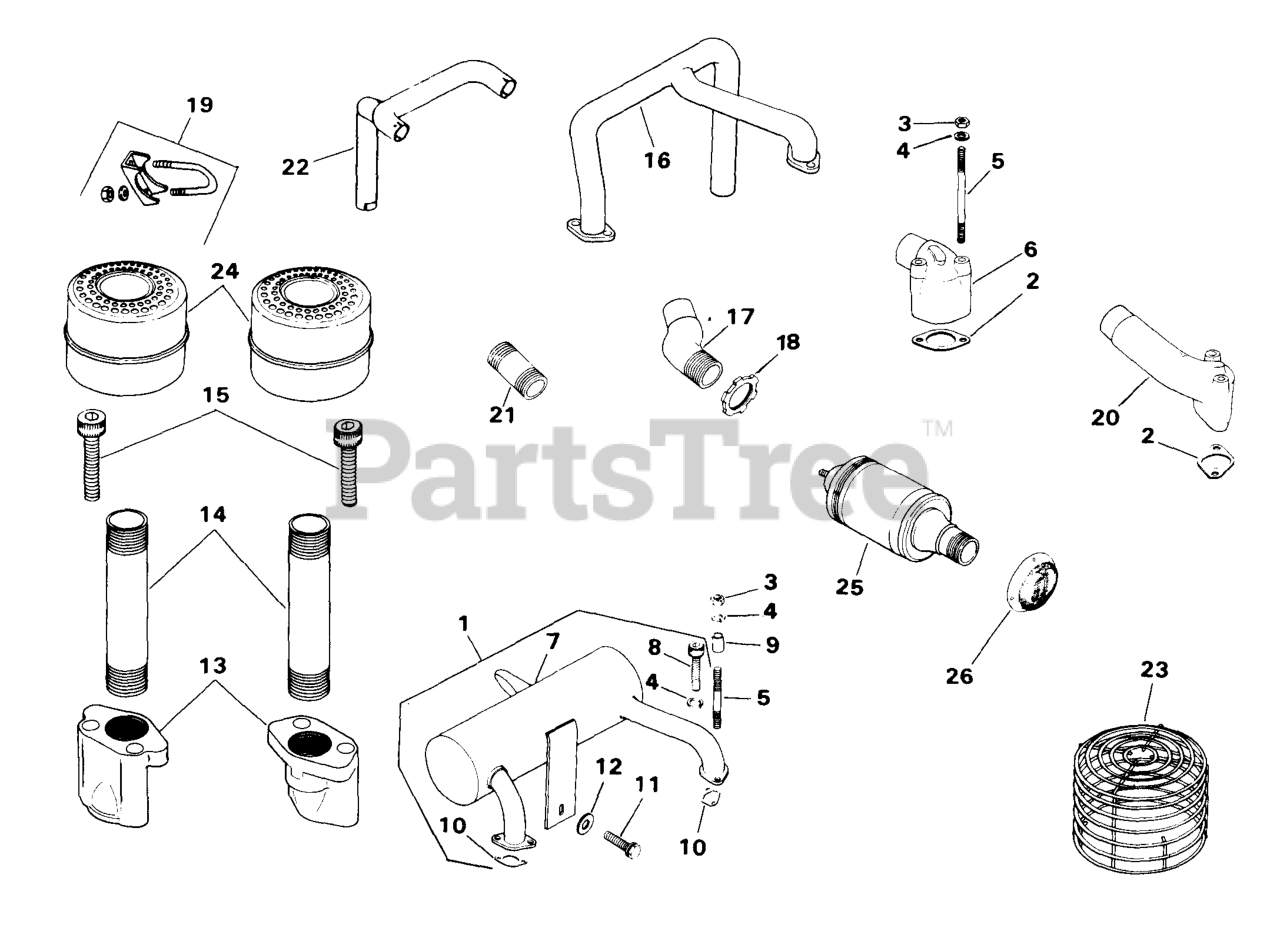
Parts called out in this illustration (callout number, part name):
4	Washer, Lock 5/16"
7	Muffler (12" Angled Extension)
8	Screw, Hex. Socket Hd. Cap 5/16-18x3/4"
10	Gasket, Exhaust
